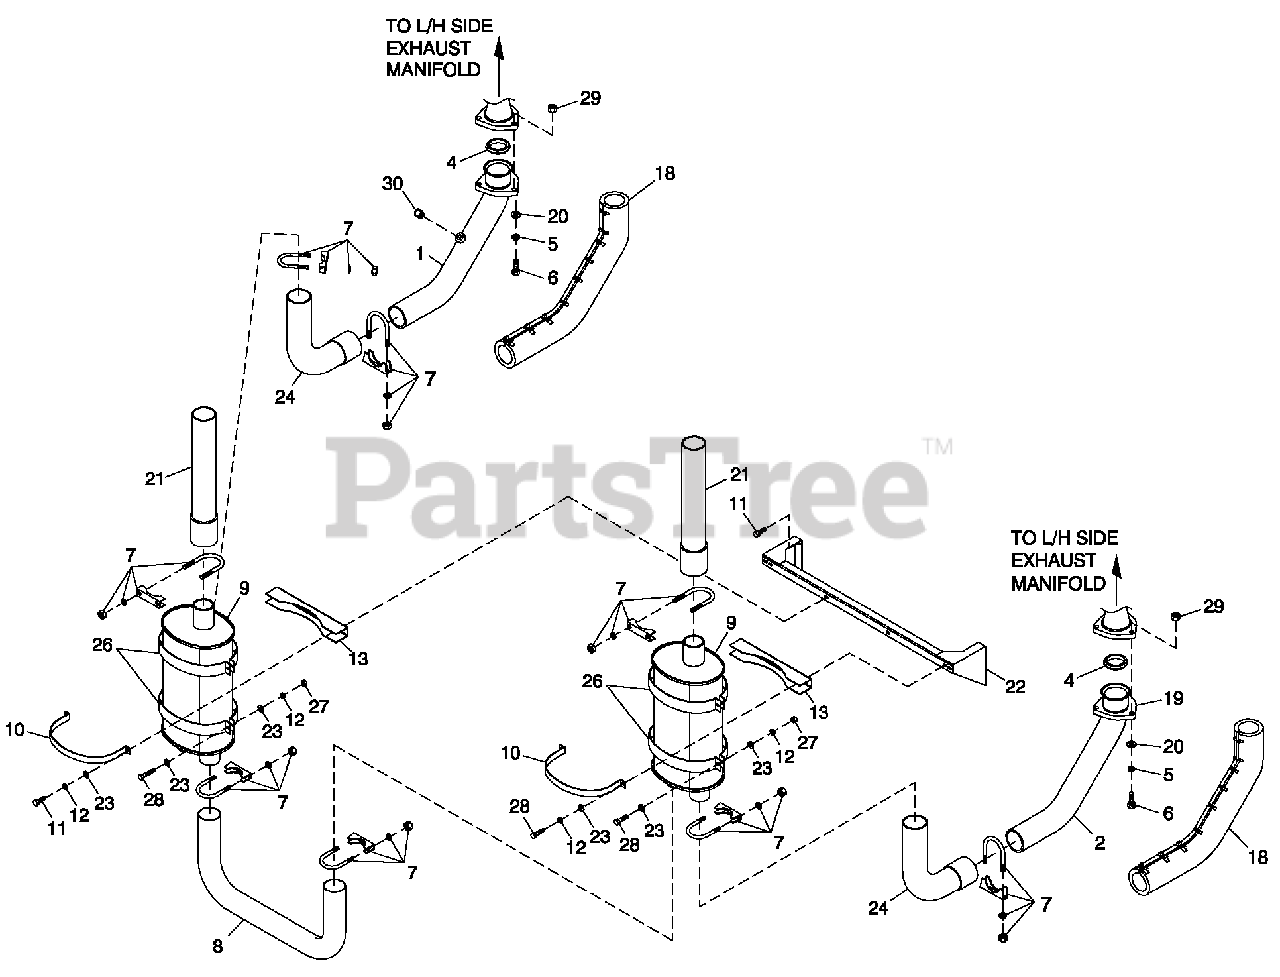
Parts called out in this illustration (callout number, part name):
1	PIPE EXH MAN R/H 6.8L G/B CPL (6.8L C5)
2	PIPE EXH MAN L/H 6.8L G/B CPL (6.8L C5)
4	RING GAS KET 2.5 DIA
5	WASHER LOCK M10S S
6	SCREW HHC M10-1.5 X 50 SS FTH
7	BOLT U 3/8-16X2.62
8	PIPE EXHAUS T CROS S OVER
9	MFLR 7" X 9" X 25" (2) 2.5" IN/2.5" OUT
10	MUFFLER STRAP
11	SCREW THF M6-1 X 16 N WA Z/JS
12	WASHER LOCK M6-1/4
13	MUFFLER BRACKET STIFFENER
18	EXHAUST BLANKET 900MM LONG (6.8L C5)
19	FLANGE EXHAUST
20	WASHER FLAT 3/8 SS
21	EXHUAST OUTLET PIPE CPL
22	BRKT MUFFLER
23	WASHER FLAT 1/4-M6 ZINC
24	PIPE ELBOW EXHAUS T MUFFLER
26	MUFFLER STRAP UPPER/LOWER
27	NUT HEX M6X 1.0 G8YEL CHR
28	SCREW HHC M6-1.0 X 35 G8.8 BLK
29	NUTHEXM10-1.5S S
30	PLUG M18-1.50
